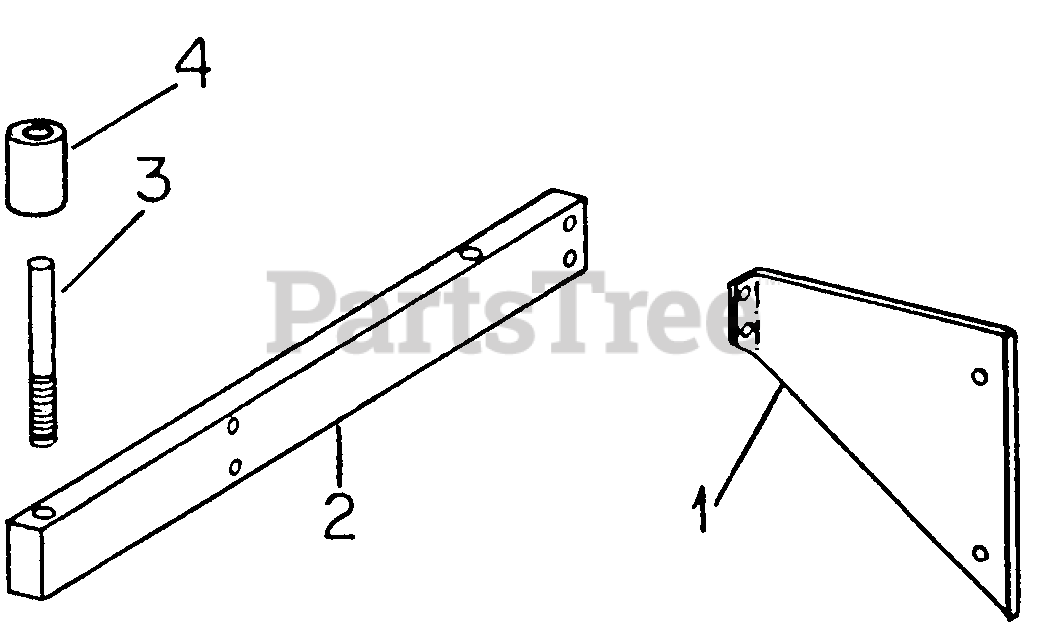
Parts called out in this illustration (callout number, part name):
1	SUPPORT, GRASS CATCHER
2	TUBE, GRASS CATCHER
3	BOLT, CYLINDER SPRING
4	SPACER, .900 X 1.125 X 4.75
